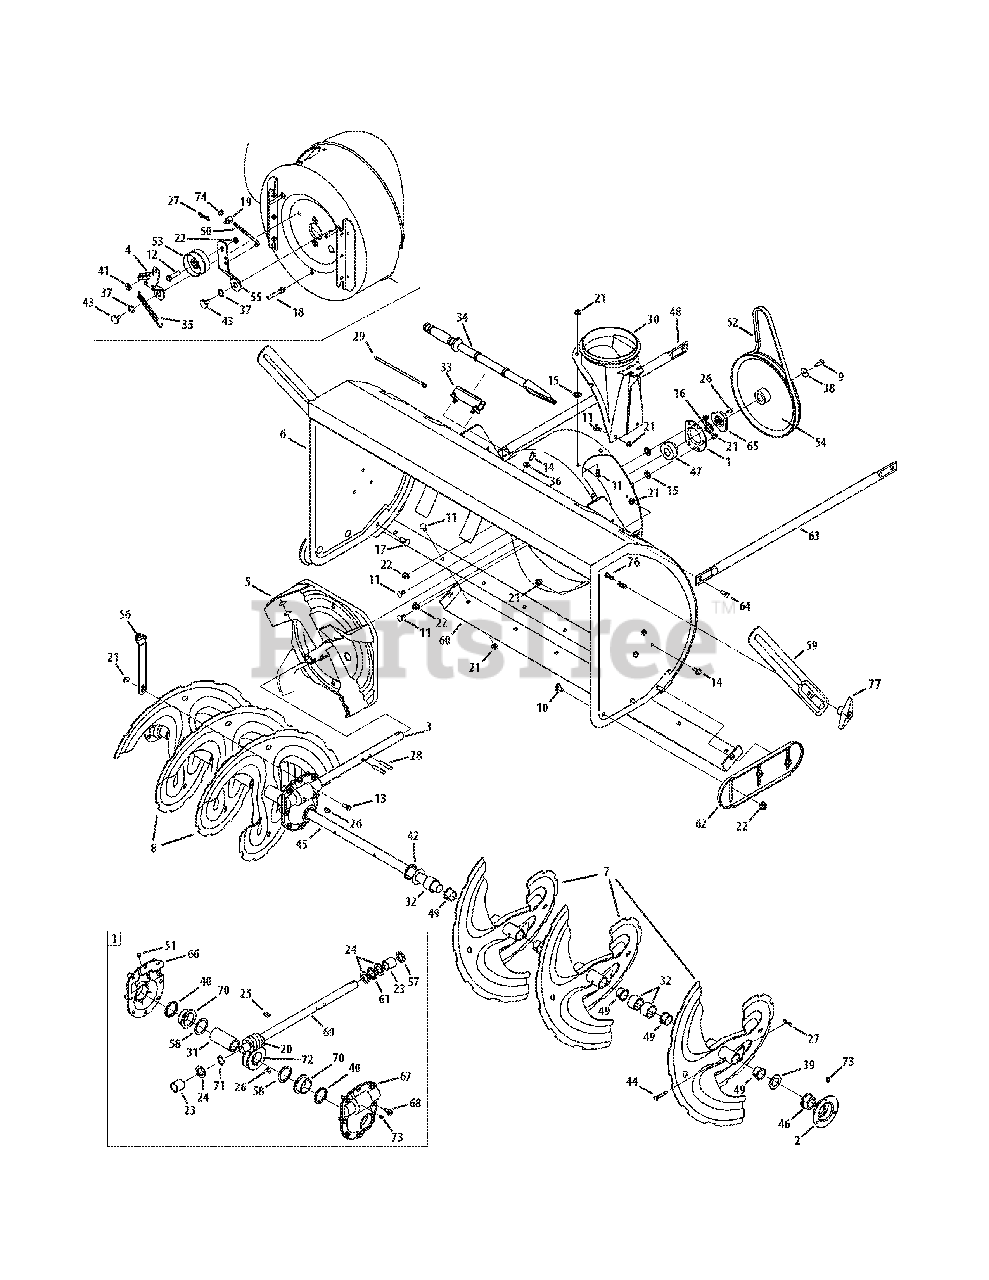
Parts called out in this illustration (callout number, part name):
1	Housing, Bearing
2	Housing, Bearing
3	Gear Box Assembly, Auger
4	Bracket Assy, Auger Brake
5	Impellar, 16"
6	Housing, Auger - 45"
7	Spiral Assy, LH
8	Spiral Assy, RH
9	Screw, 5/16-24 x .875
10	Bolt, Carriage, 3/8-16 x 1.00
11	Screw, Carriage, 5/16-18 x .75
12	Screw, Hex Cap, 3/8-16 x 1.75
13	Screw, Hex Cap, 5/16-18 x 1.00
14	Screw, 5/16-18 x .750
15	Nut, Push
16	Washer, ..76 x 1.49 x .06
17	Bolt, Carriage, 3/8-16 x 1.25
18	Screw, 5/16-18 x .4300
19	Ferrule
20	Gear, Worm, Dbl Thread
21	Nut, Flnge Lk, 5/16-18
22	Nut, Flg Lk, 3/8-16
23	Sleeve
24	Washer, Flat, .88 ID x .38 OD
25	Key, Hi Pro, 3/16 x 3/4
26	Key, Woodruff,1/4 x 3/4
27	Pin, Bowtie Cotter
28	Pin, Spirol, 5/16 x 1.75
29	Tie, Cable
30	Adapter, Chute, 6"
31	Shaft, Gear, Worm
32	Spacer, 1.0 x 1.5 x 1
33	Clip, Mounting
34	Tool, Cleanout
35	Spring, Extension
36	Washer, .349 x .879 x .063
37	Washer, .625 x .885 x .015
38	Washer, Flat, .34 x 1.50 x .150
39	Spacer, 1.004 x 1.375 x .25
40	Oil Seal
41	Washer, .344 x .75 x .12
42	Washer, 1.01 x 1.86 x .06
43	Screw, Shoulder, .625 x .17
44	Pin, Shear, .25 x 1.75
45	Axle, Spiral, 45"
46	Bearing, Flange w/Flats
47	Bearing, Self Aligning
48	Tube, Support, RH
49	Bushing, Flange, 1.051 x 1.16
50	Rod, Auger Idler
52	V Belt,4L x 44.60" Long
53	Pulley, Flat Idler, 2.75 OD
54	Pulley, Auger Drive, 10.0
55	Bracket, Auger Idler
56	Bracket, Gear Box Support
57	Seal, Oil
58	Washer, Flat, 1.52 ID x 2.0 OD
59	Drift Cutter
60	Plate, Shave, 45"
61	Bearing, Thrust
62	Shoe, Skid
63	Tube, Support , LH
64	Screw, 5/16-18 x .75
65	Pulley, Adapter, .75 Dia.
66	Hsg Assy Auger RH (Inc. 40 & 70)
67	Hsg Assy Auger LH (Inc. 40 & 70)
68	Screw, LD, 5/16-18 x .750
69	Shaft, Drive, Auger
70	Flange Bearing
71	Ext, Ret, Ring
72	Gear, Worm, LH
73	Lube Fitting, 3/16 #70
74	Jam Nut, 5/16-18
75	Flat Washer, .385 x .870 x .092
76	Screw, Carriage, 5/16-18 x 1.0
77	Wing Knob
